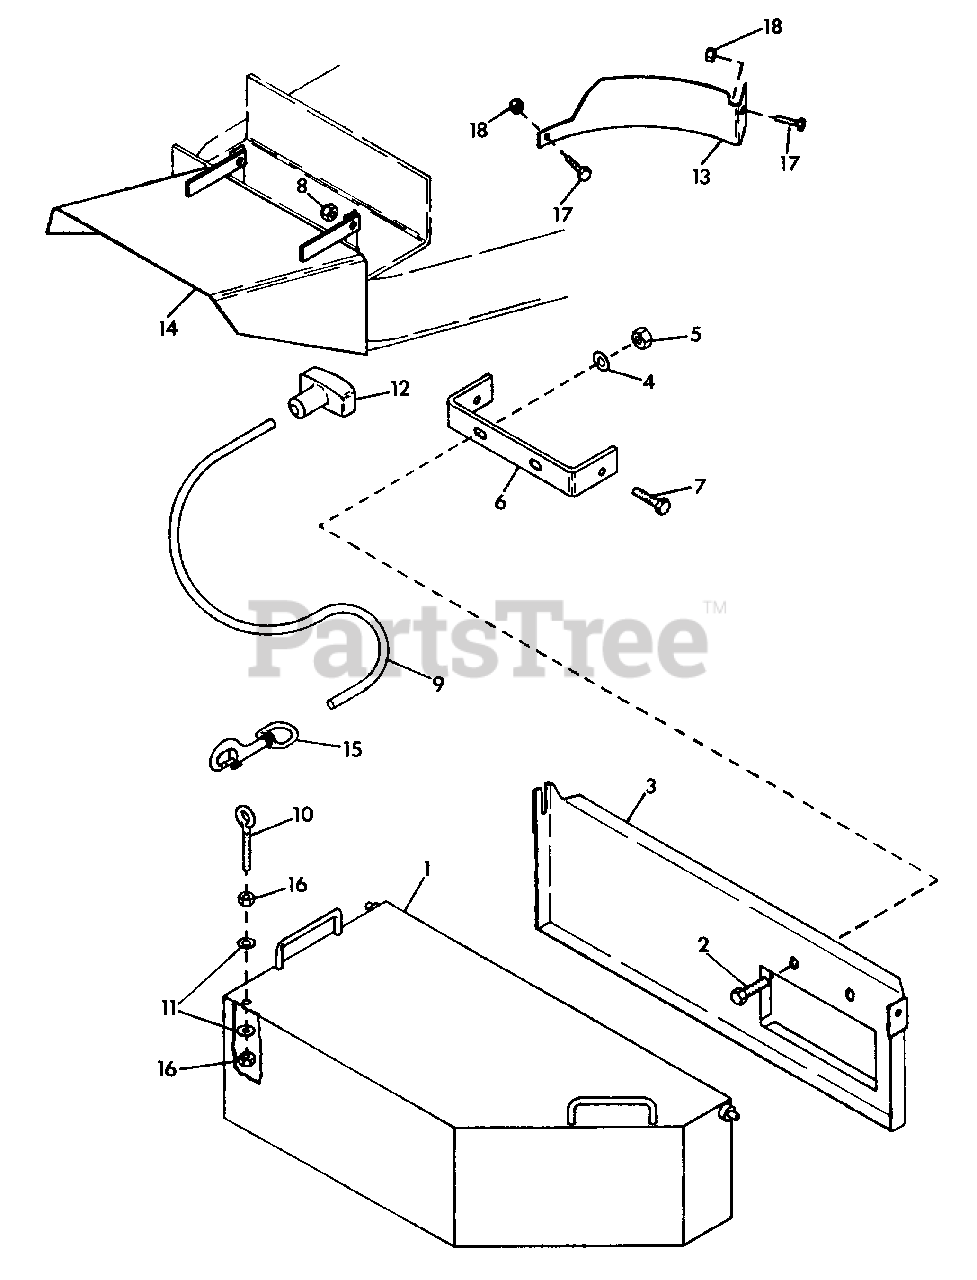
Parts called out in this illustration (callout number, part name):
1	WELDMENT, GRASS CATCHER
2	BOLT, HEX 3/8-16X1.00
3	WELDMENT, FRAME SUPPORT
4	WASHER, FLAT .406X.812X.065
5	NUT, LOCK 3/8-16
6	BRACKET
7	BOLT, HEX 5/16-18X1.25
8	NUT, LOCK 5/16-18
9	ROPE, #6 66"
10	BOLT, EYE
11	WASHER, FLAT .312X.734X.065
12	HANDLE
13	BAFFLE
14	WELDMENT, DISCHARGE CHUTE
15	SNAP, SWIVEL EYE BOLT
16	NUT, HEX 5/16-18
17	BOLT, 1/4-20X.75 RD HD SQ NK
18	NUT, LOCK 1/4-20
